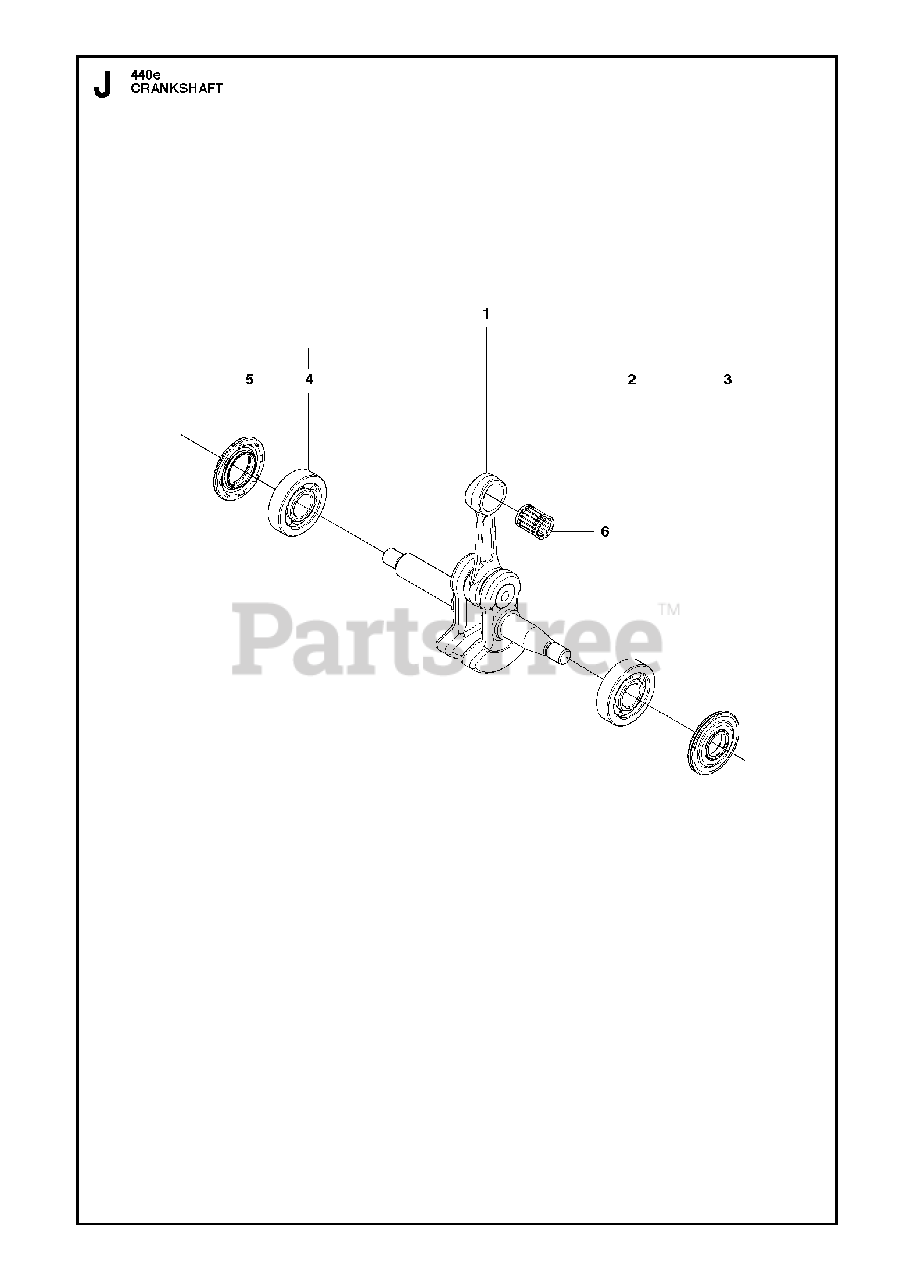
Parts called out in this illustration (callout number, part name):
1	CRANKSHAFT ASSY
2	BALL BEARING
3	SEALING
4	BALL BEARING
5	SEALING
6	SUPPORT BUSHING
